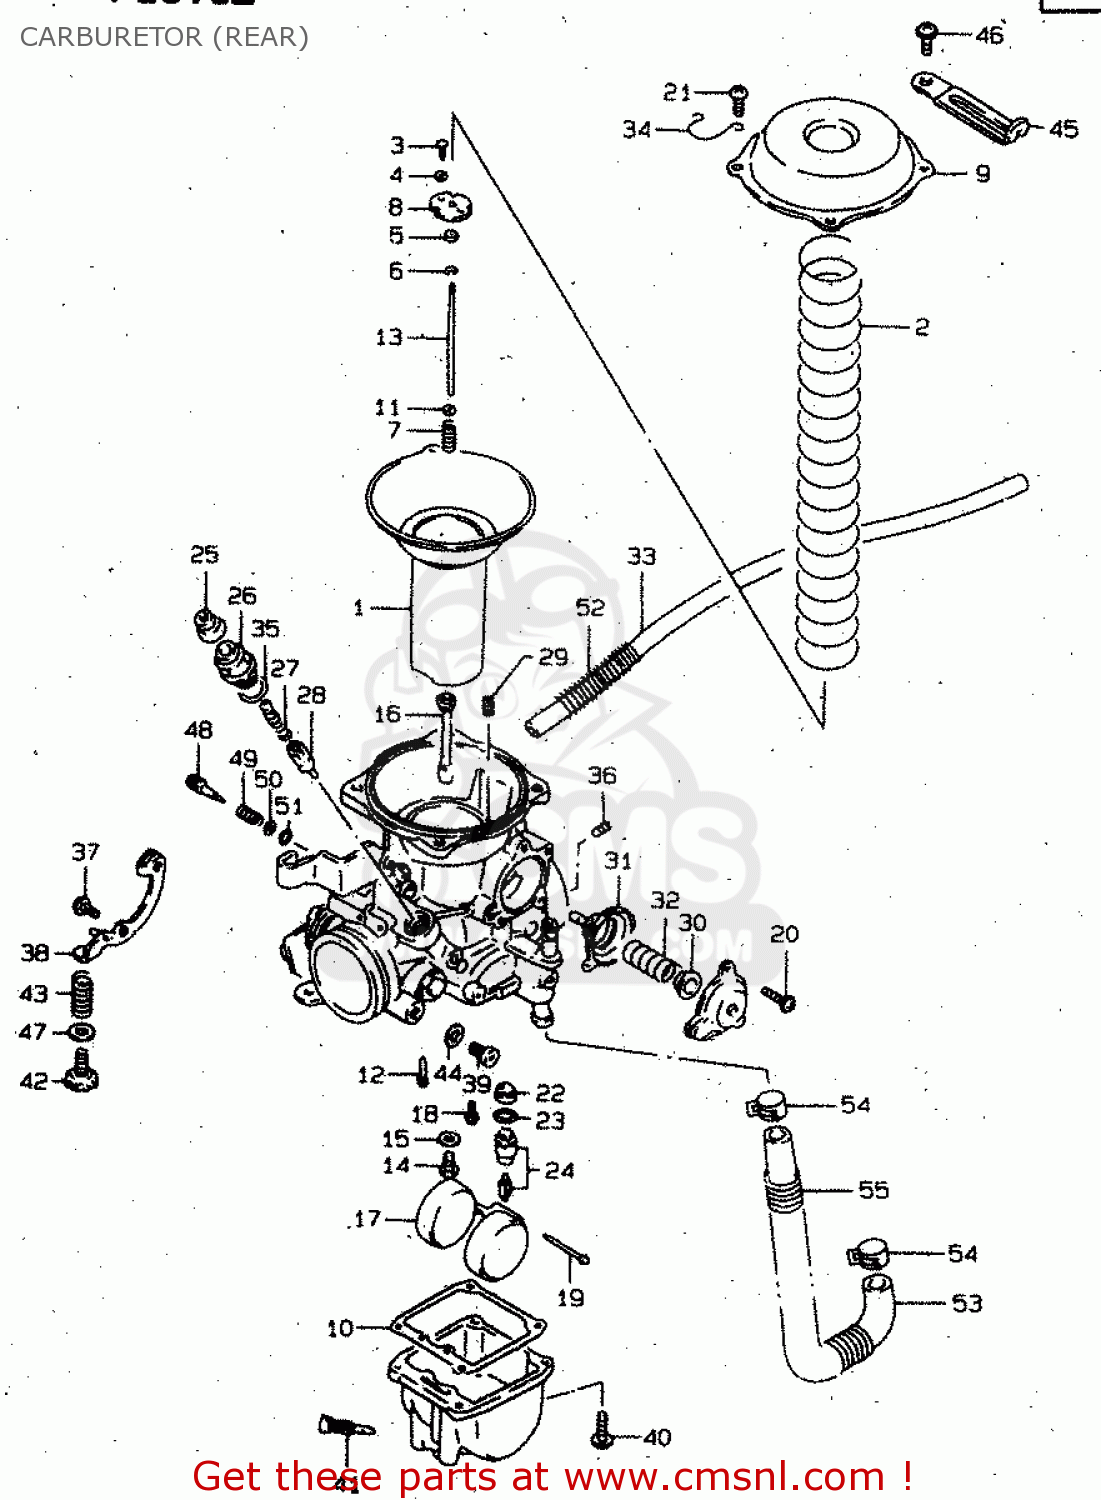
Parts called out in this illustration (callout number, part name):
1	DIAPHRAGM ASSY
2	SPRING,DIAPHRAGM
3	SCREW
4	WASHER,LOCK
5	RING
6	CLIP
7	SPRING
8	PLATE
9	COVER,DIAPHRAGM
10	GASKET,FLOAT CHAMBER (NAS)
11	WASHER
12	JET,PILOT
13	NEEDLE,JET
14	JET,MAIN(130)
15	WASHER
16	JET,NEEDLE(P-3)
17	FLOAT
18	SCREW
19	PIN,FLOAT
20	SCREW
21	SCREW
22	FILTER
23	O-RING,NEEDLE VALVE
24	VALVE ASSY,NEEDLE
25	CAP
26	HOLDER,GUIDE
27	SPRING
28	PLUNGER,STARTER
29	JET,AIR(1.9)
30	PLATE
31	DIAPHRAGM ASSY
32	SPRING
33	HOSE(5X8.2X600)
34	CLIP
35	O RING
36	JET,AIR(60)
37	SCREW
38	LEVER ASSY
39	SCREW
40	SCREW
41	SCREW,DRAIN
42	ADJUSTER
43	SPRING
44	WASHER
45	CLAMP(L:65)
46	SCREW
47	WASHER
48	SCREW,PILOT
49	SPRING
50	WASHER
51	O RING,PILOT AIR SCREW
52	SPRING
53	HOSE,FUEL PUMP & CARBURETOR
54	CLIP
55	SPRING
